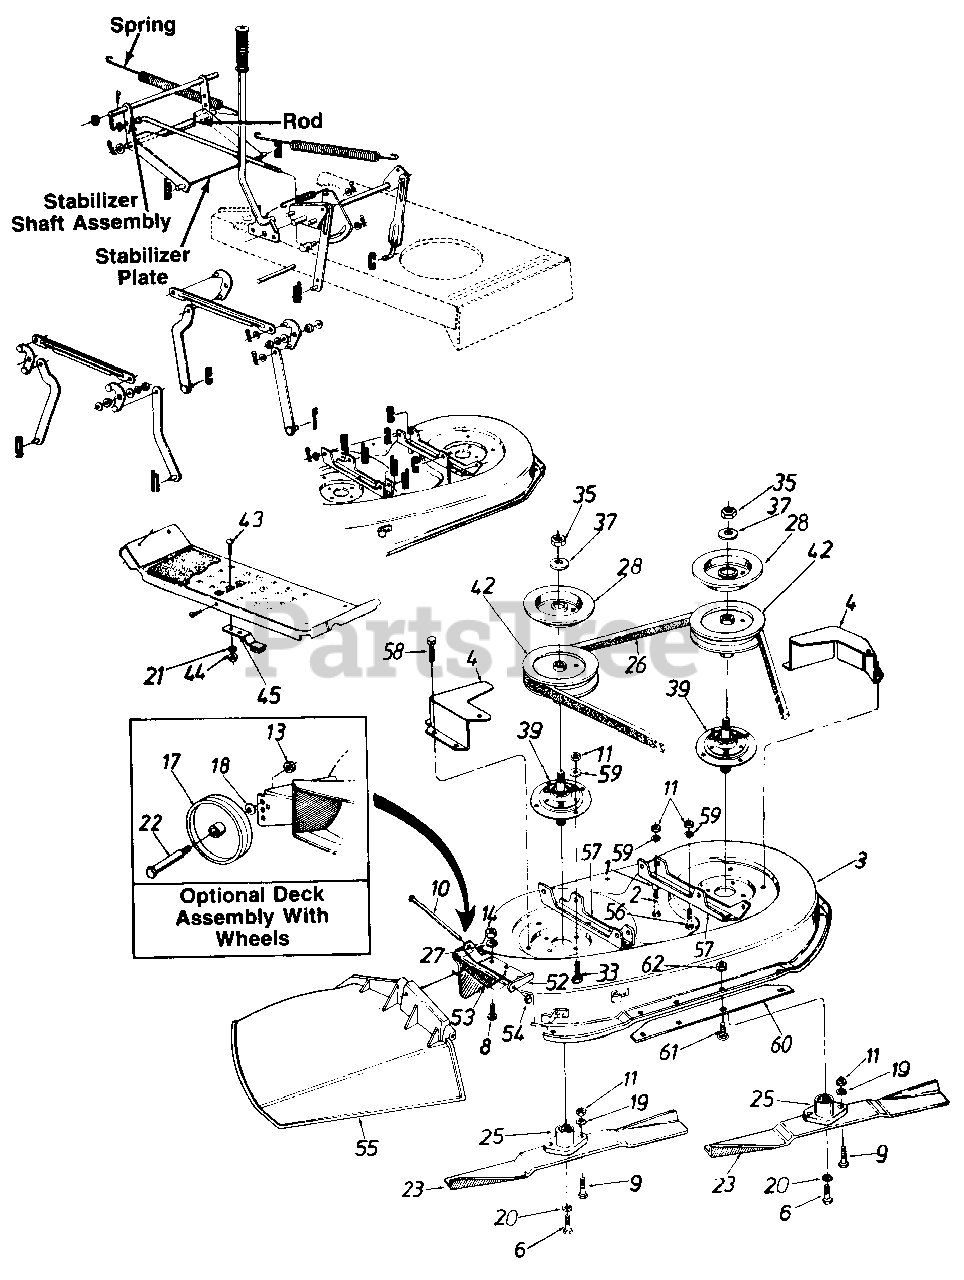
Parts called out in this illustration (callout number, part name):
1	Spacer .33" I.D. x .88"
2	Hex Bolt 5/16-24 x 1.25" Lg.
3	38" Deck Ass'y. w/Deck Wheels
6	Hex Bolt 3/8-24 x 1.0" Lg.
8	Hex Bolt 1/4-20 x .62"
9	Hex Bolt Special 5/16-24 x 1.0"
10	Hinge Pin
11	Hex Nut 5/16-24 Thd
13	Hex Top L-Nut 3/8-16 Thd.
14	Hex Nut 1/4-20 Thd.
17	Deck Wheel 5"
18	Bell-Wash. .40" I.D. x .88" O.D.
19	L-Wash. 5/16" I.D.
20	L-Wash. 3/8" I.D. H.D.
21	L-Wash. 1/4" I.D.
22	Shld. Bolt .498" Dia. x 1.53"
23	High-Lift Blade
25	Blade Adapter
26	V-Belt
27	Bell -Wash. 1/4" I.D.
28	Brake Disc
33	Hex Bolt 5/16-24 x .75" Lg.
35	Hex Jam Nut 5/8-18 Thd.
37	L-Wash. 5/8" I.D.
39	Blade Spindle Ass'y. Comp.
42	5" Dia. Pulley
43	Carr. Bolt 1/4-20 x .62"
44	Hex Nut 1/4-20 Thd.
45	Blade Brake Ass'y.
52	Hinge Mtg. Brkt.
53	Torsion Spring
54	Push Nut
55	Chute Ass'y. Comp.
56	Hex Bolt 5/16-24 x .75" Lg.
59	Bell-Wash. .345" I.D. x .88"
62	Hex Sems Nut 1/4-20 Thd.
17665-0483	Belt Guard, Black - CHARCOAL GRAY (0483)
17665-0498	Belt Guard, Black - OLD CUB YELLOW (0498)
17665-0637	Belt Guard, Black - POWDER BLACK (0637)
17665-0638	Belt Guard, Black - MTD/TROY-BILT RED (0638)
17665-0648	Belt Guard, Black - TECH GRAY (0648)
17665-0650	Belt Guard, Black - RED METALLIC (0650)
17665-0662	Belt Guard, Black - OYSTER GRAY (0662)
17665-0665	Belt Guard, Black - YARDMAN GREEN (0665)
